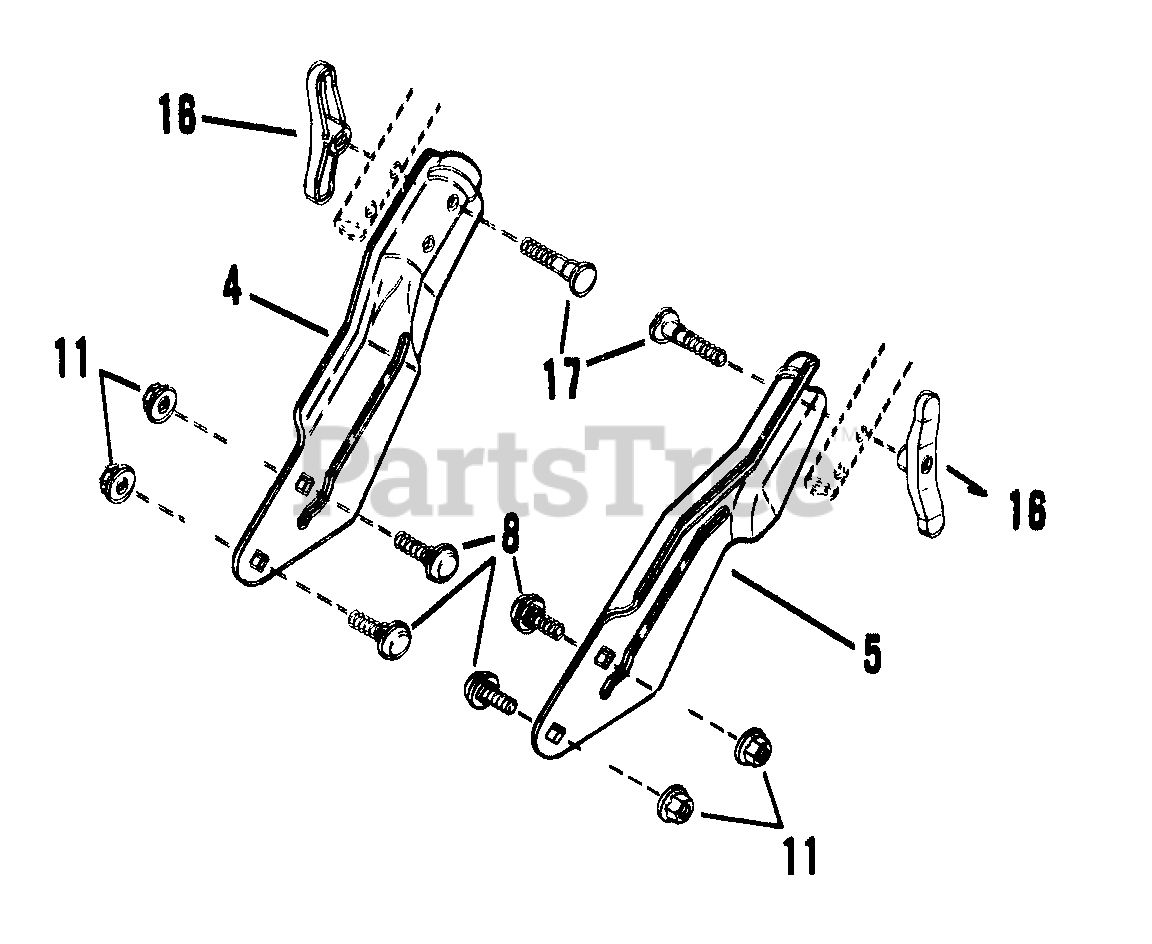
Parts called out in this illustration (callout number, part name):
4	HANDLE, Lower R. H.
5	HANDLE, Lower L. H.
8	BOLT, 5/16-18 x 5/8" Short Neck Carriage
11	NUT, 5/16-18 Hex Flange Lock
16	NUT, 1/4-20 Wing
17	SCREW, 1/4-20 x 1-3/8" Curved Head
